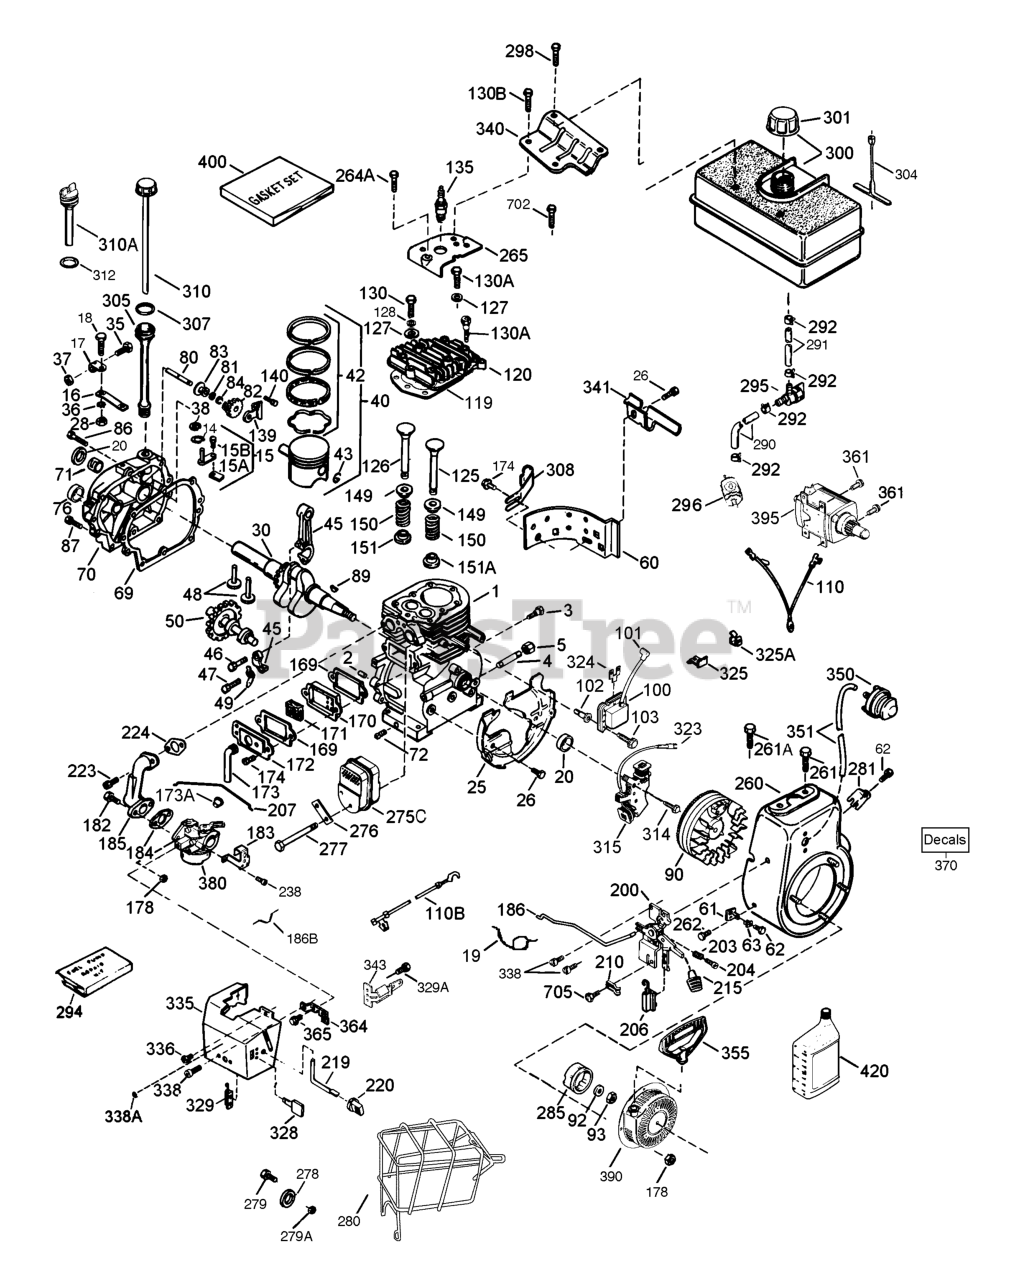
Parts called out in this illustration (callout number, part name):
1	CYLINDER
4	Oil Drain Extension Purchase Locally
5	PIPE CAP
15	GOVERNOR ROD
15A	GOV YOKE
16	GOV LEVER
20	OIL SEAL
30	CRANKSHAFT
38	RET RING
40	PISTON ASSY 010
40	PISTON ASSY STD
41	PISTON ASSY STD
41	PISTON ASSY 010
42	RING SET 010
42	RING SET STD
43	RET RING
45	CONN ROD
47	SCREW
48	VALVE LIFTER
49	OIL DIPPER
50	CAMSHAFT
60	EXTENSION
70	CYL COVER
71	BUSHING
72	PIPE PLUG
80	GOV SHAFT
83	GOV SPOOL
84	RET RING
90	FLYWHEEL
100	LAMINATION
101	PLUG COVER
110	GROUND WIRE
120	CYL HEAD-NLA
125	EXH VALVE OS
125	EXH VALVE STD
126	INT VALVE ST
135	SPARK PLUG
139	BRACKET
140	SCREW
149	VALVE CAP
150	VALVE SPRING
151	VALVE CAP
151A	INT VALVE SEAL
170	BREATHER
171	ELEMENT
172	VALVE COVER
183	BRACKET
185	INTAKE PIPE
186	GOV LINK
200	CONTROL ASSY
203	COMP SPRING
206	TERMINAL
207	GOV LINK
219	CHOKE ROD
238	SCREW
260	BLOWER HSG
275C	MUFFLER
276	LOCK PLATE
285	STARTER CUP
291	FUEL LINE
300	FUEL TANK
301	FUEL CAP
311	DIPSTICK
315	ALT COIL
323	TERMINAL
328	KEY
335	CARB COVER
340	TANK BRACKET
341	TANK BRACKET
343	BRACKET
351	PRIMER LINE
355	START HANDLE
364	BRACKET
370	DECAL
380	CARBURETOR
390	STARTER
400	GASKET SET
420	OIL SAE 5W30
999	MAINTENANCE KIT
